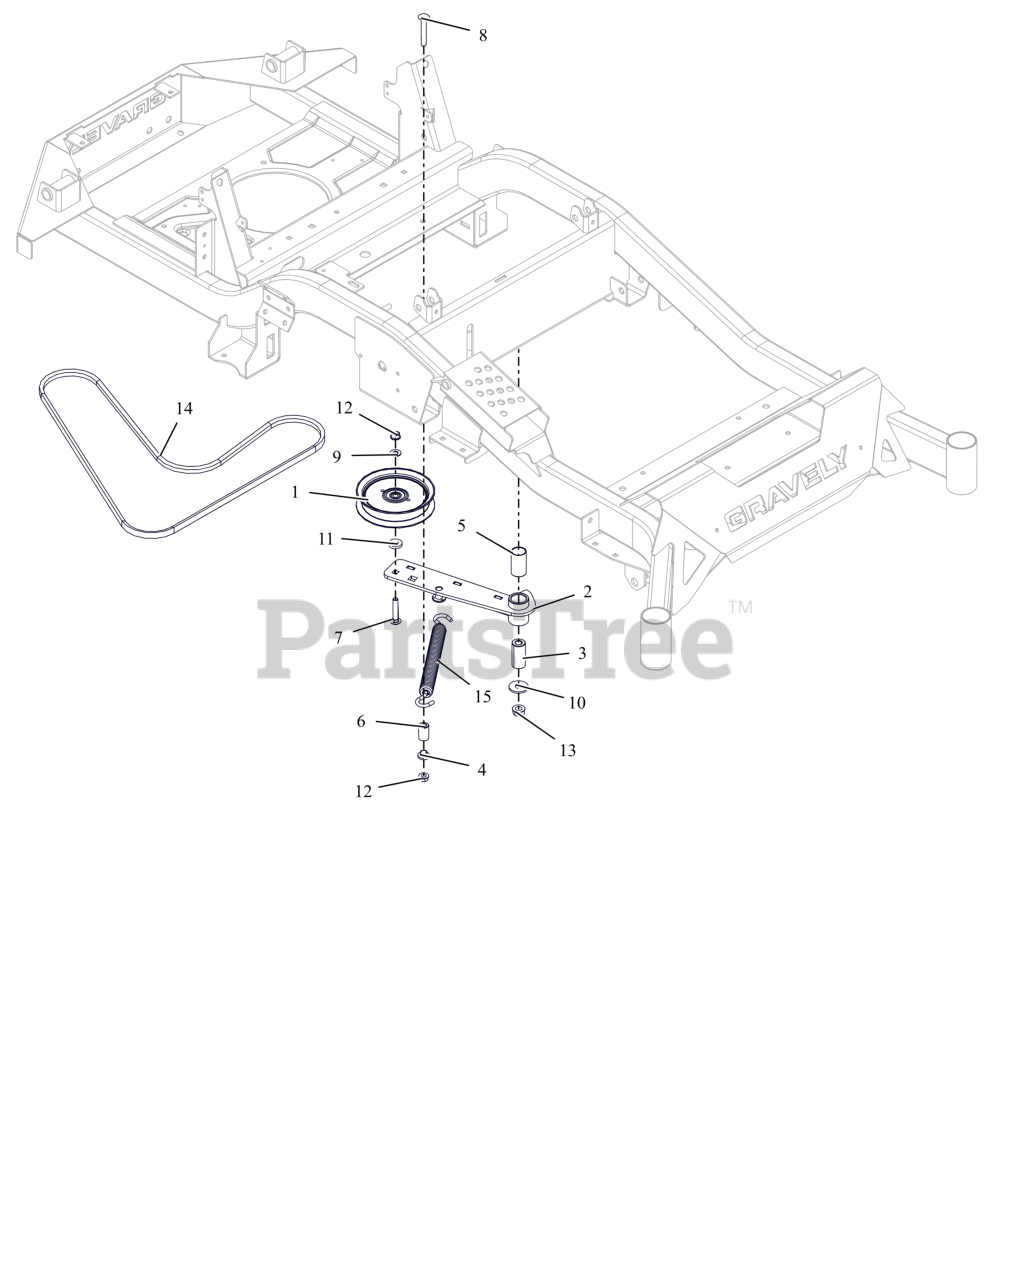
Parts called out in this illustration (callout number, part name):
1	IDLER, FLAT 5.00"
2	WLDMT, HYDRO DRIVE IDLER ARM (BLACK)
3	BSHG, SPCR .502X.997X2.03 PM
4	BSHG-FLG .385X.500X.875X.406
5	BSHG, 1.00X1.125X1.937
6	BUSHING, SLV .380X.750X1.190
7	BLT, RHSN .38-16X2.00 G5 ZCC
8	BLT, RHSSN.38-16X2.50 G5 ZCC
9	WSHR,FLT .406X.812X.065 ZCC
10	WSHR-FL-STL.511X1.44X.125ZC120
11	WSHR, FLT .406X1.00X.188 ZCC
12	NUT-LK-TOP-FLG .38-16 ZC120
13	NUT-LK-TOP-FLG .500-13 GF ZCC
14	V-BELT, 4L-WRAPPED
15	SPRING, EXTENSION
